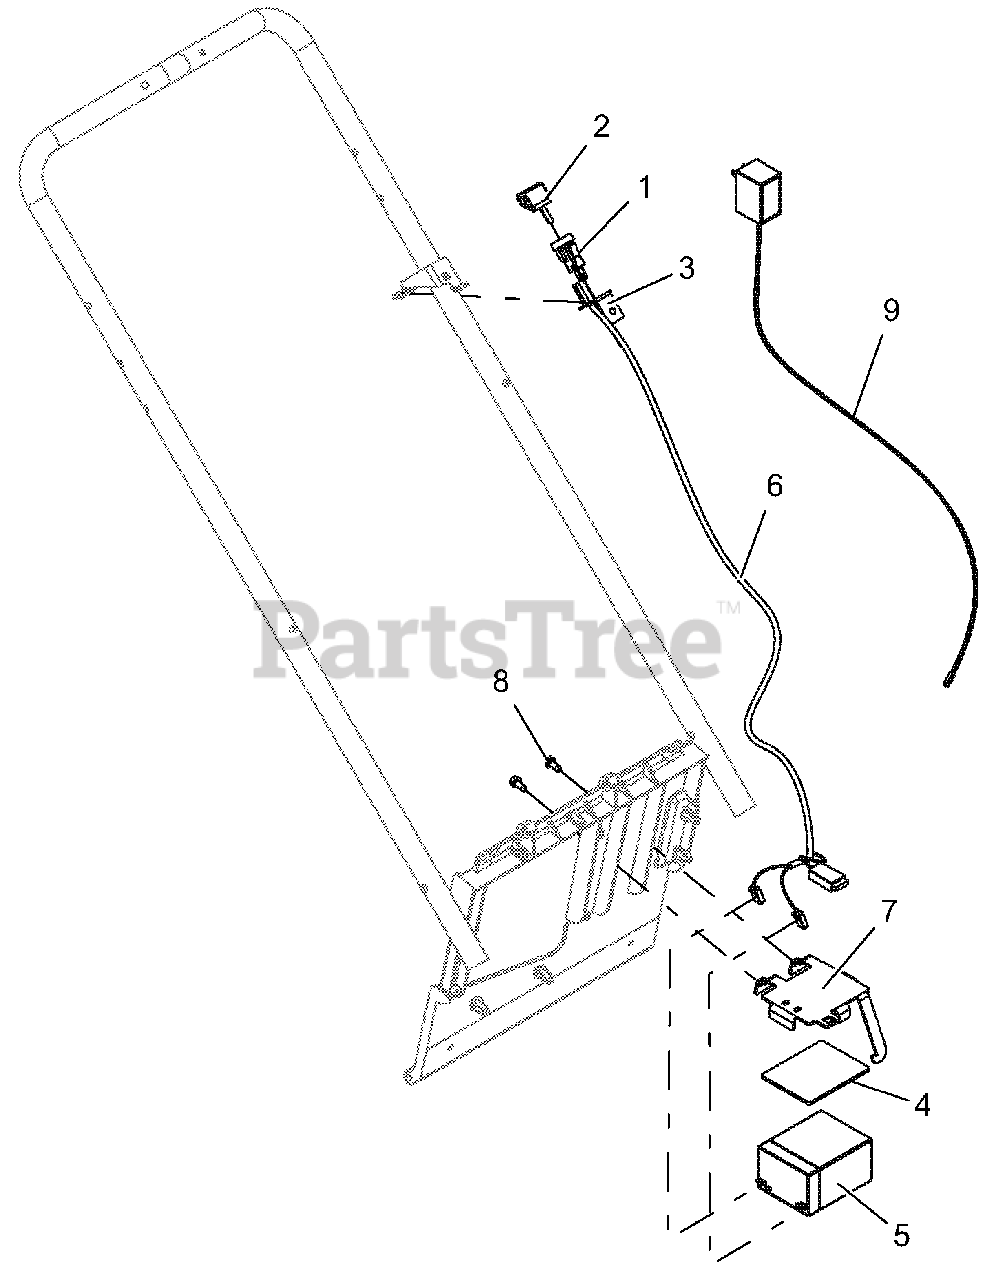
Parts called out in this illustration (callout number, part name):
1	SWITCH, KEY
2	KEY, LM ELEC START
3	BRKT, KEY SWITCH
4	PAD, BATTERY , LM
5	BATTERY, AGM, 2.9AH, GNRL PRPS
6	HARNESS, ELEC START
7	BRKT, BATTERY HOLD DOWN (BLACK)
8	SCR-TAP .25-20X.50 HWH TR YWZ
9	CHARGER, BATTERY
